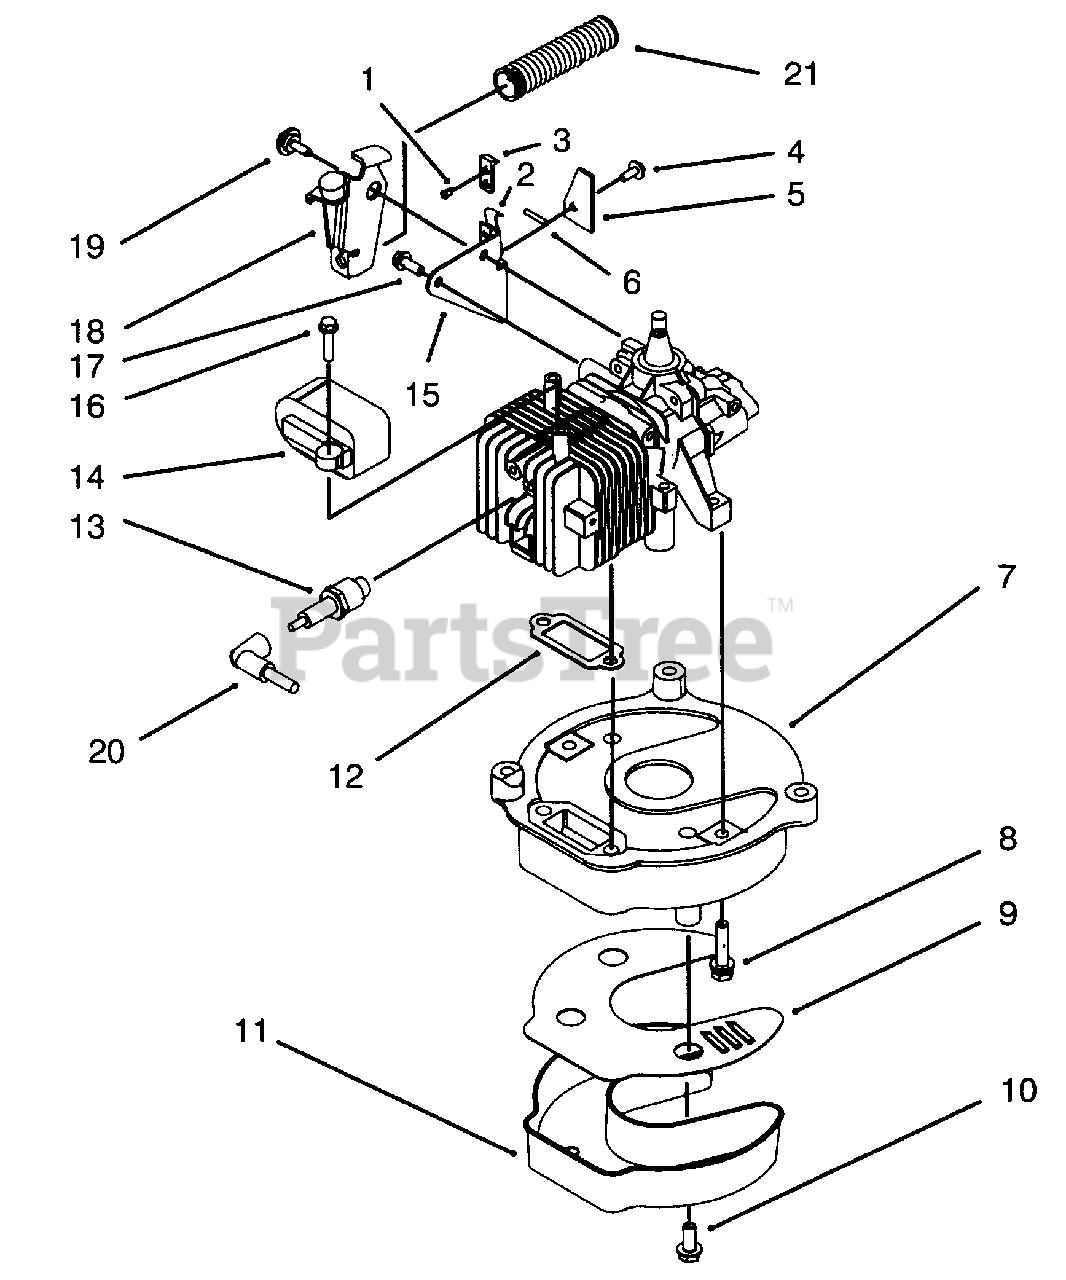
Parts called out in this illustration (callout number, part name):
2	Strap-Ground
3	Strap-Insulation
4	Screw-Thread Forming
5	Stop-Ground Strap
6	Wire-Brake Switch Lead
7	Plate-Muffler
11	Cover-Muffler
12	Gasket-Exhaust
13	Plug-Spark
14	Ignition Assembly (Incl. Ref. #20)
15	Plate-Brake Mount
16	Screw-Hex Washer Hd.
17	Screw
18	Plate-Brake Assembly
19	Screw-Shoulder
20	Lead & Cover Assembly
21	Spring-Compression
